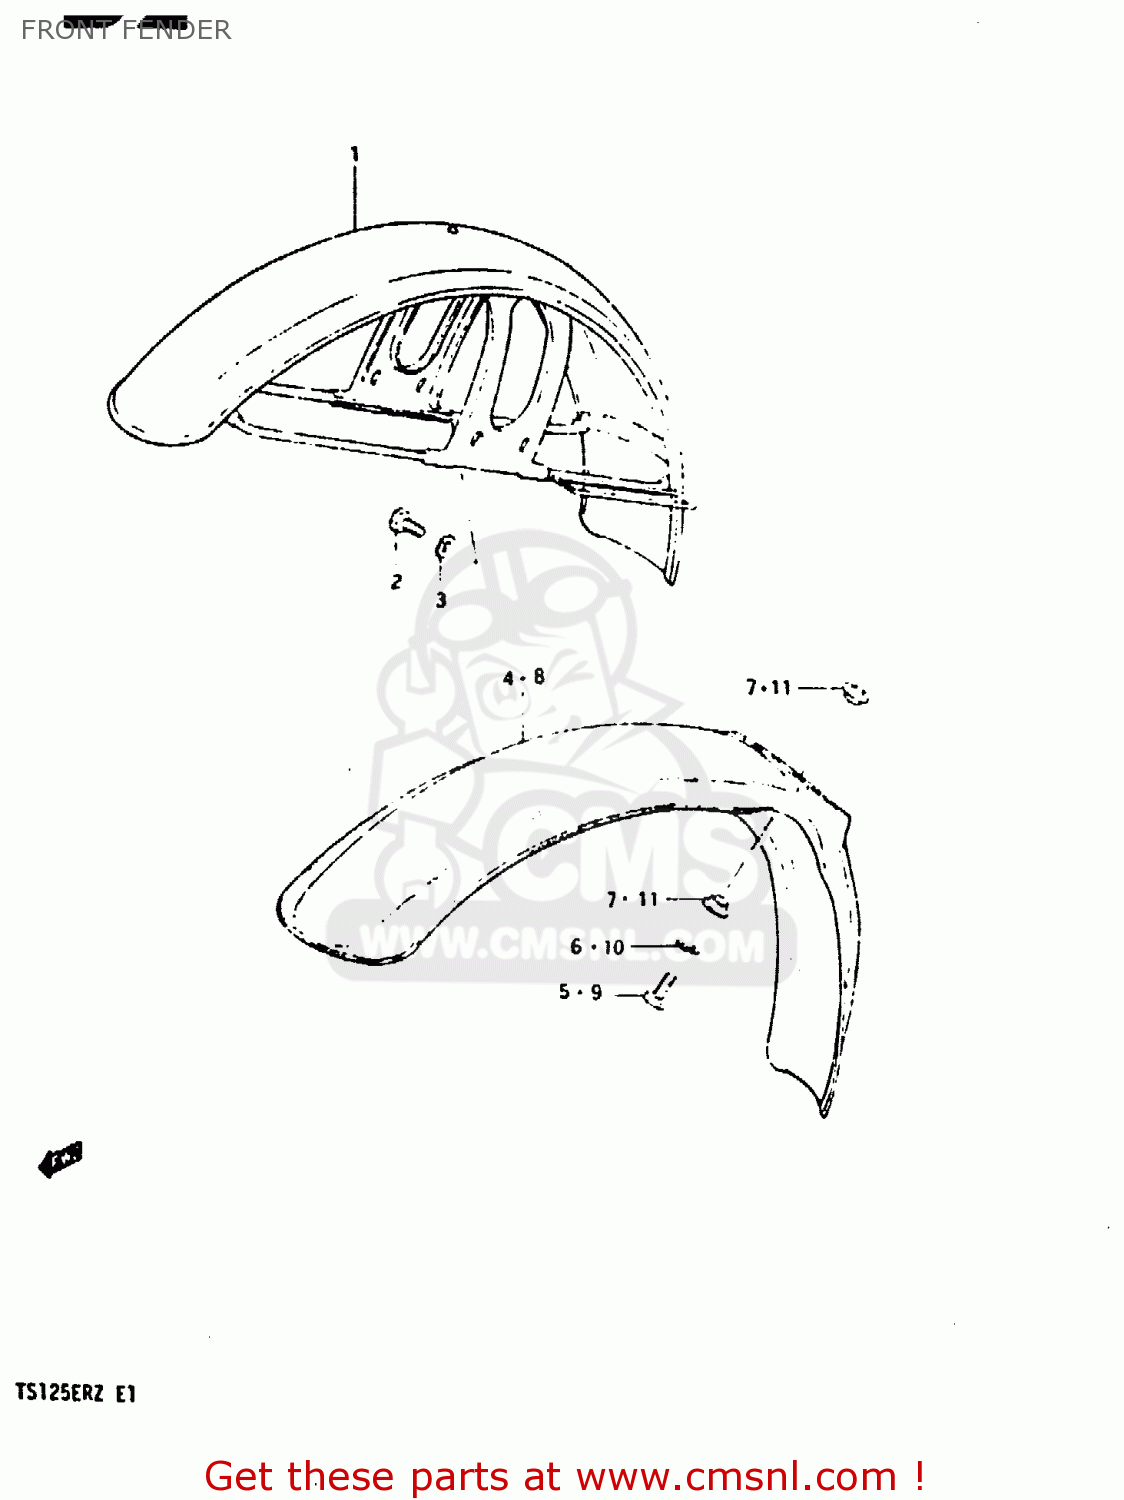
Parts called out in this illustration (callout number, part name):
1	FENDER,FR
2	BOLT
3	LOCK WASHER
4	FENDER, FRONT (RED)
5	BOLT, UPPER
6	LOCK WASHER
7	SPACER
